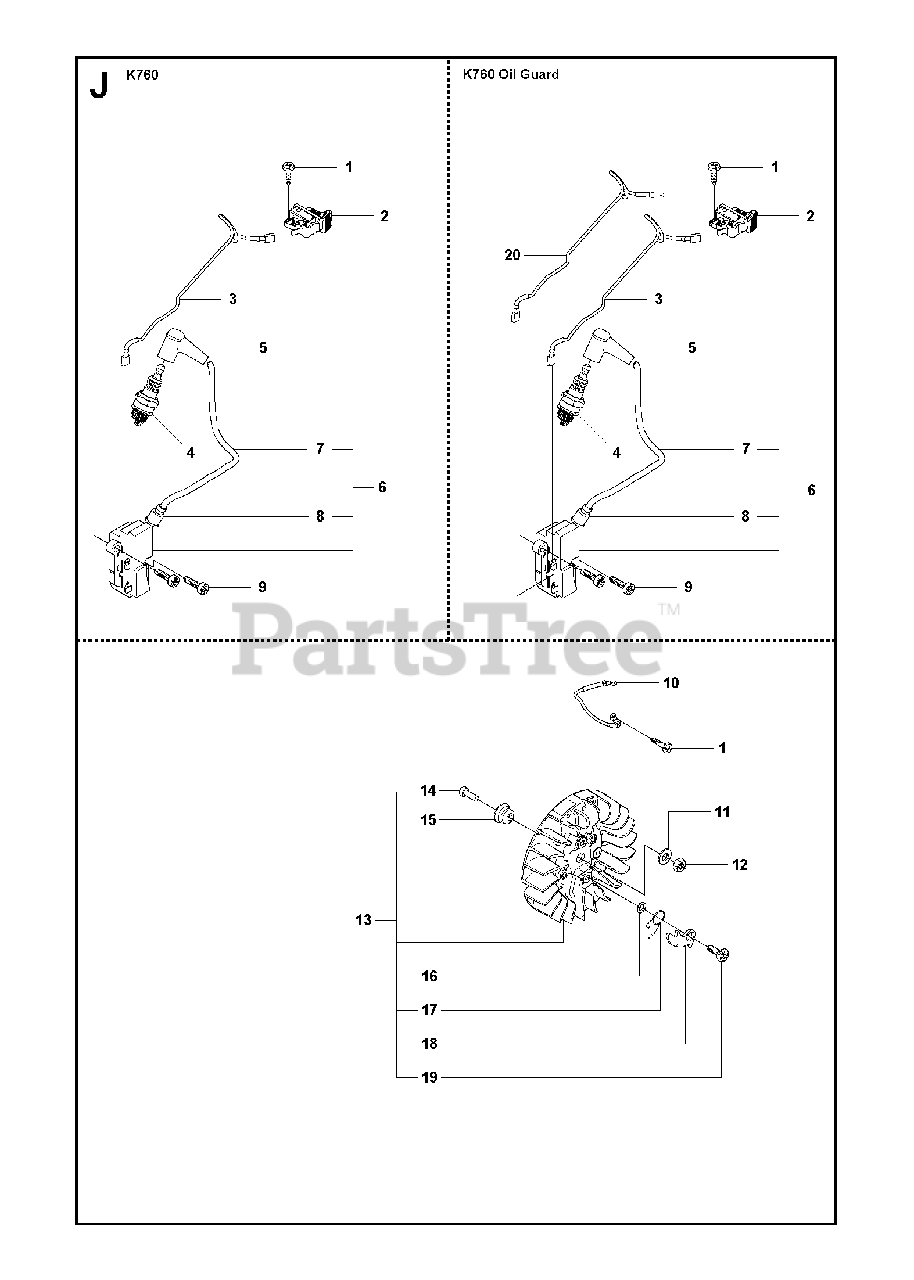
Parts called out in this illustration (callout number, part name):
1	SCREW CCRPANT
2	STOP SWITCH
3	CABLE
3	CABLEOil Guard
5	SPARK PLUG CAP
6	IGNITION MODULEIncl. 7 - 8
7	IGNITION CABLE
9	SCREW ITXSCM
13	FLYWHEELIncl. 14 - 19
14	SCREW IHSCM
19	SCREW
20	CABLEOil Guard
